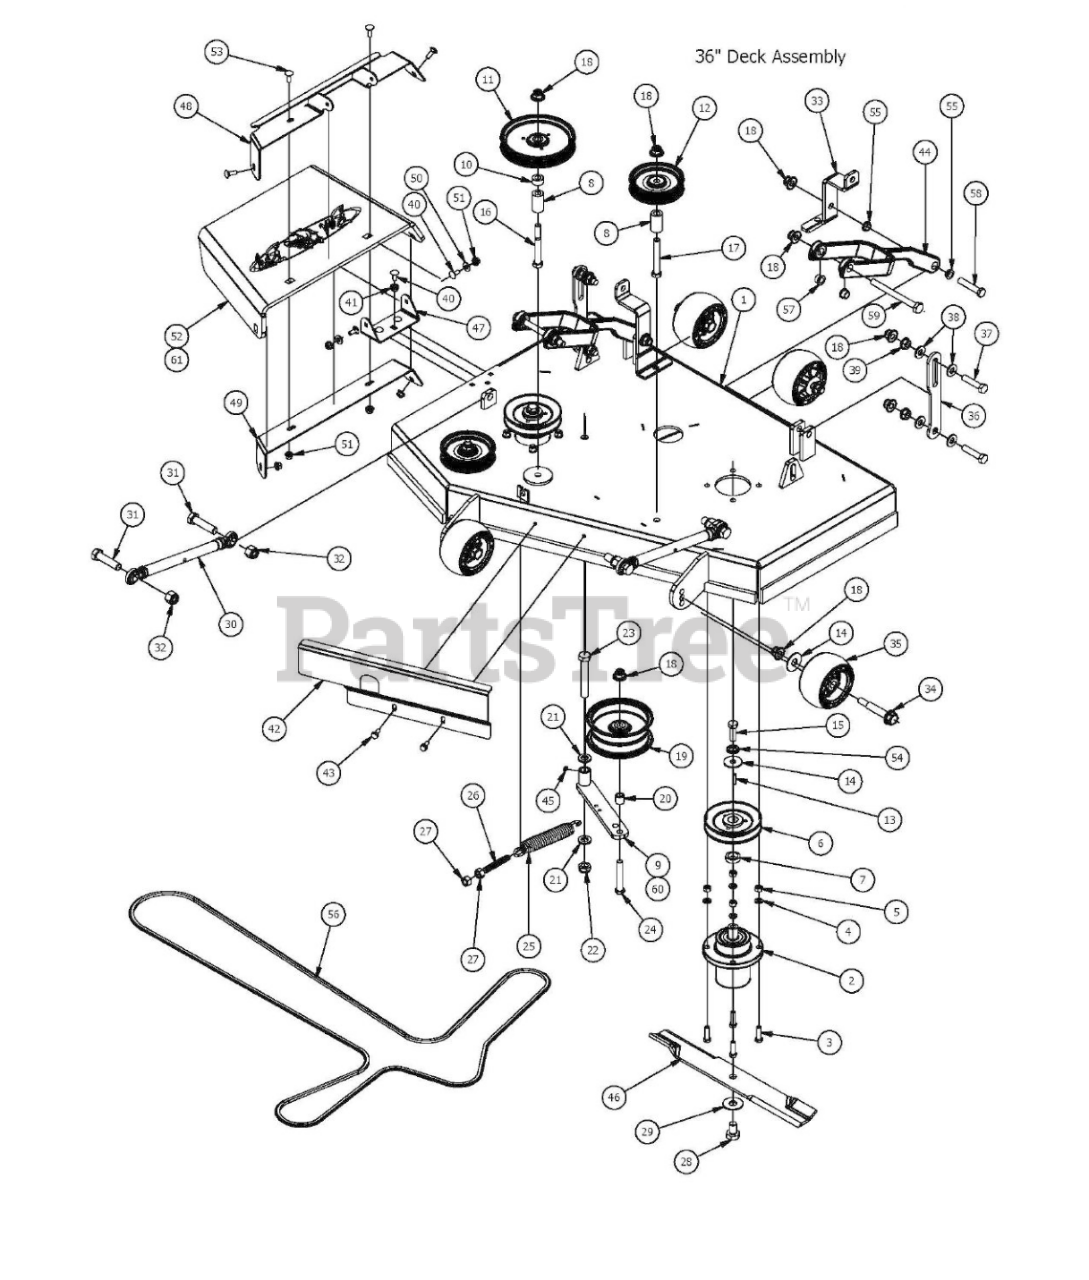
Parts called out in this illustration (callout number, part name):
1	36 Stand On Deck
2	Spindle Assembly
3	3/8" x 1 1/4" Hex Bolt
4	3/8" Lock Washer
5	3/8" Hex Nut
6	Deck Pulley
7	36 Deck Spindle Spacer
8	1 3/4" Pulley Spacer
9	Deck Idler
10	1/2 Solid Shaft Collar (W/1 Set Screw) Zinc
11	5-3/4 Idler Pulley-Don Dye
12	5 V Idler Pulley 1/2" Bore
13	3/16 x 1 Square Key
14	1/2" Belleville Washer
15	1/2"-20 x 1 1/2 - Grade 5 Fine Thread Bolt
16	1/2" x 4" Bolt (Grade 8)
17	1/2 x 3 1/2 Flange Bolt Grade 8
18	1/2-13 Nylon Flange Nut
19	5 3/4" Deck Idler Pulley
20	Spacer 3/4 OD x 1/2 ID x 314 Length
21	.630 ID X 1.122 OD X .142 THK Flat Washer Nylon
22	5/8" Nylock (1/2 Jam)
23	5/8" x 4" Hex Bolt
24	1/2-13 x GR 5 Hex Bolt Zinc
25	2009 Deck/Pump Idler Spring
26	All Thread-Pump Idler Tensioner
27	1/2" Hex Nut
28	5/8" x 1 1/2" Grade 8 Hex Bolt (Fine)
29	5/8" Flat Washer
30	Turnbuckle (Top Link)
31	5/8" x 2 1/2" Grade 5 Hex Bolt (Coarse)
32	5/8 Std NC Nylock Nut
33	Stand-On Deck Stop
34	Deck Wheel Bolt
35	Anti-Scalp Roller
36	Longer deck hanger
37	1/2-13X 2-1/4 GR Hex Bolts
38	.505 Nylon Spacer
39	1/2" Flange Nut
40	5/16-18 X 3/4 Carriage Bolt
41	5/16" Nylock Flange Nut
42	36 Stand-On Deck Shield
43	5/16 x 3/4 washer head type F screw
44	Deck Arm Assembly
45	1/4" Press in Grease Fitting
46	54" Deck Fusion Blade For Outlaw
47	Chute Hanger 48 MZ
48	Discharge Chute Bracket (Upper)
49	Discharge Chute Bracket (Lower)
50	.360 ID Plastic Washer
51	5/16" Flange Nut
52	Rubber Discharge Chute
53	5/16" x 7/8" Carriage Bolt
54	1/2" Lock Washer Zinc
55	Flange Bushing For Lower Deck Arm
56	36 inch Deck Belt -B111
57	Flange Bushing For Upper Deck Arm
58	1/2" x 3" Hex Bolt
59	1/2" x 5 1/2" Bolt
60	Idler Arm Assembly
61	Chute Assembly
